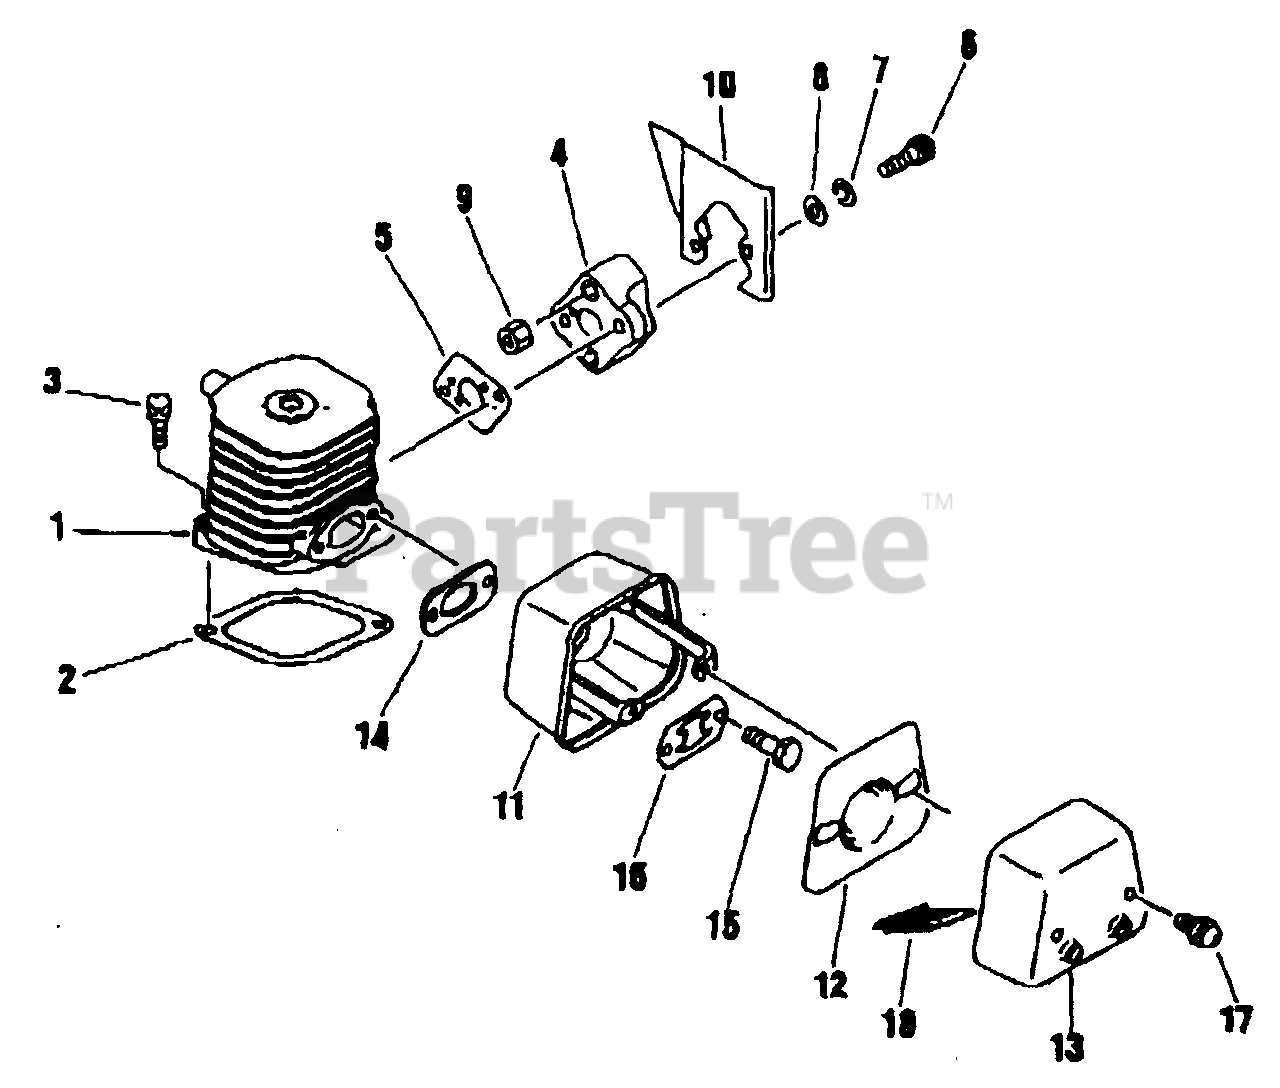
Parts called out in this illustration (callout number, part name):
1	CYLINDER
3	BOLT M5×20
4	INSULATOR
5	GASKET
6	BOLT M5×18
7	WASHER, SPRING 5
8	WASHER, FLAT 5.5×10×0.8
9	NUT M5×6.3
10	AIR GUIDE
11	MUFFLER BASE
12	MUFFLER PLATE
13	COVER, MUFFLER
14	GASKET, EXHAUST
15	BOLT
16	LOCKWASHER
17	SCREW
18	SCREEN, SPARK ARRESTER
